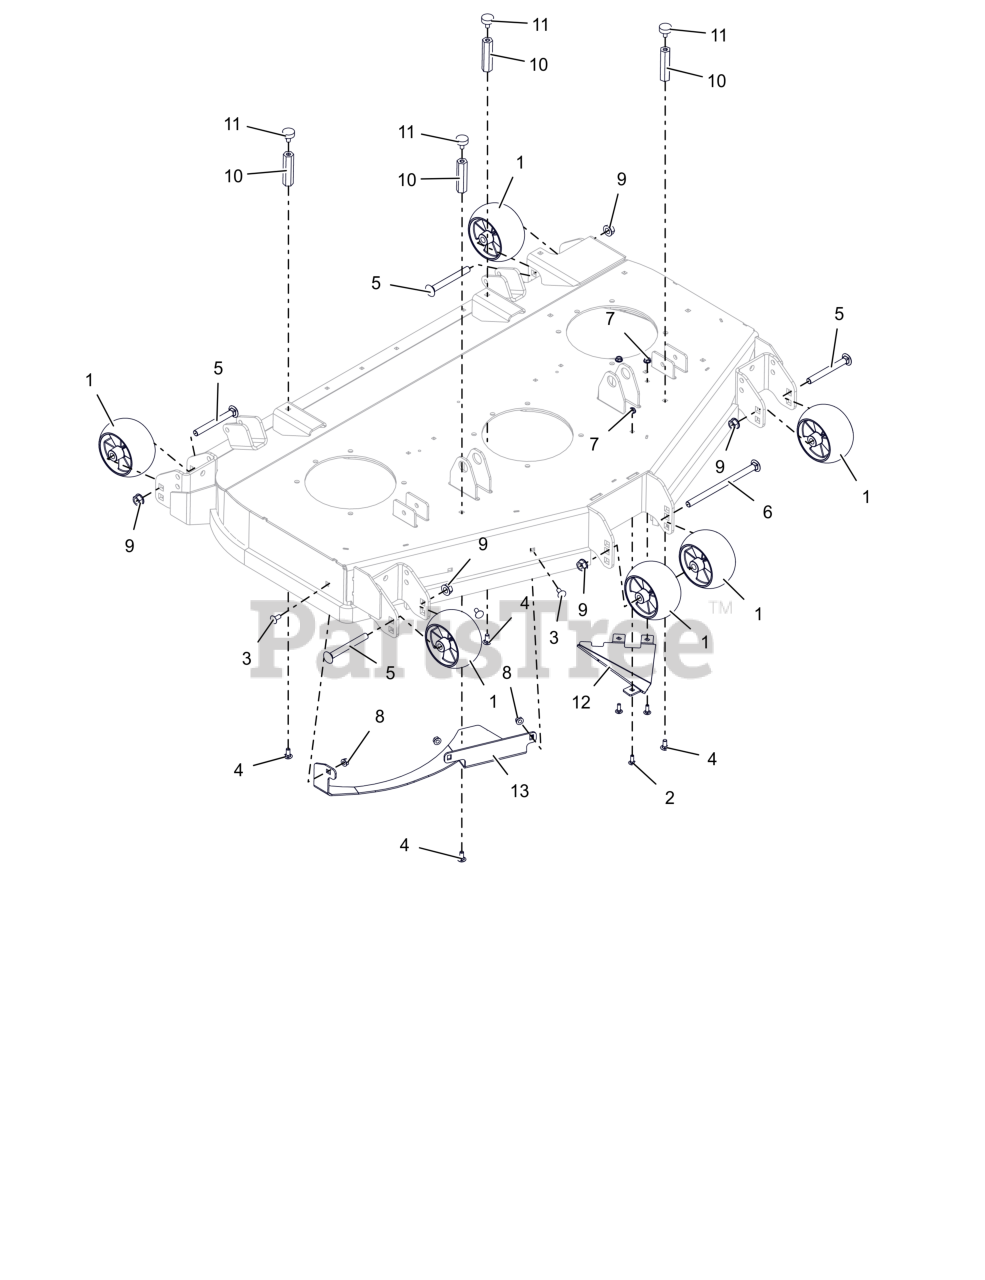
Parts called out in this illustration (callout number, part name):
1	WHEEL, ANTI SCALP - 5X3 CTR W/RIBS
2	BLT, RHSN .25-20X.750 G5 ZCC
3	BLT, RHSSN.31-18X.750 G5 ZCC
4	BTL,RHSN .313-18 X 0.75 G5 ZCC LT
5	BLT,RHNS .50-13X4.50 G5 ZCC NS
6	BLT,RHSN .50-13X8.00 G5 ZCC NS
7	NUT-LK-CTR-FLG .25-20 ZC120
8	NUT,LK-CTR-FLG .31-18 GF ZCC
9	NUT-LK-CTR-FLG .500-13 GG ZCC
10	NUT, COUPLING .31-18 X 3.00
11	BUMPER, RUBBER
12	BAFFLE, 48" TRIANGLULAR INSERT (RED)
13	DEFLECTOR, BAFFLE BOLT-IN (RED)
